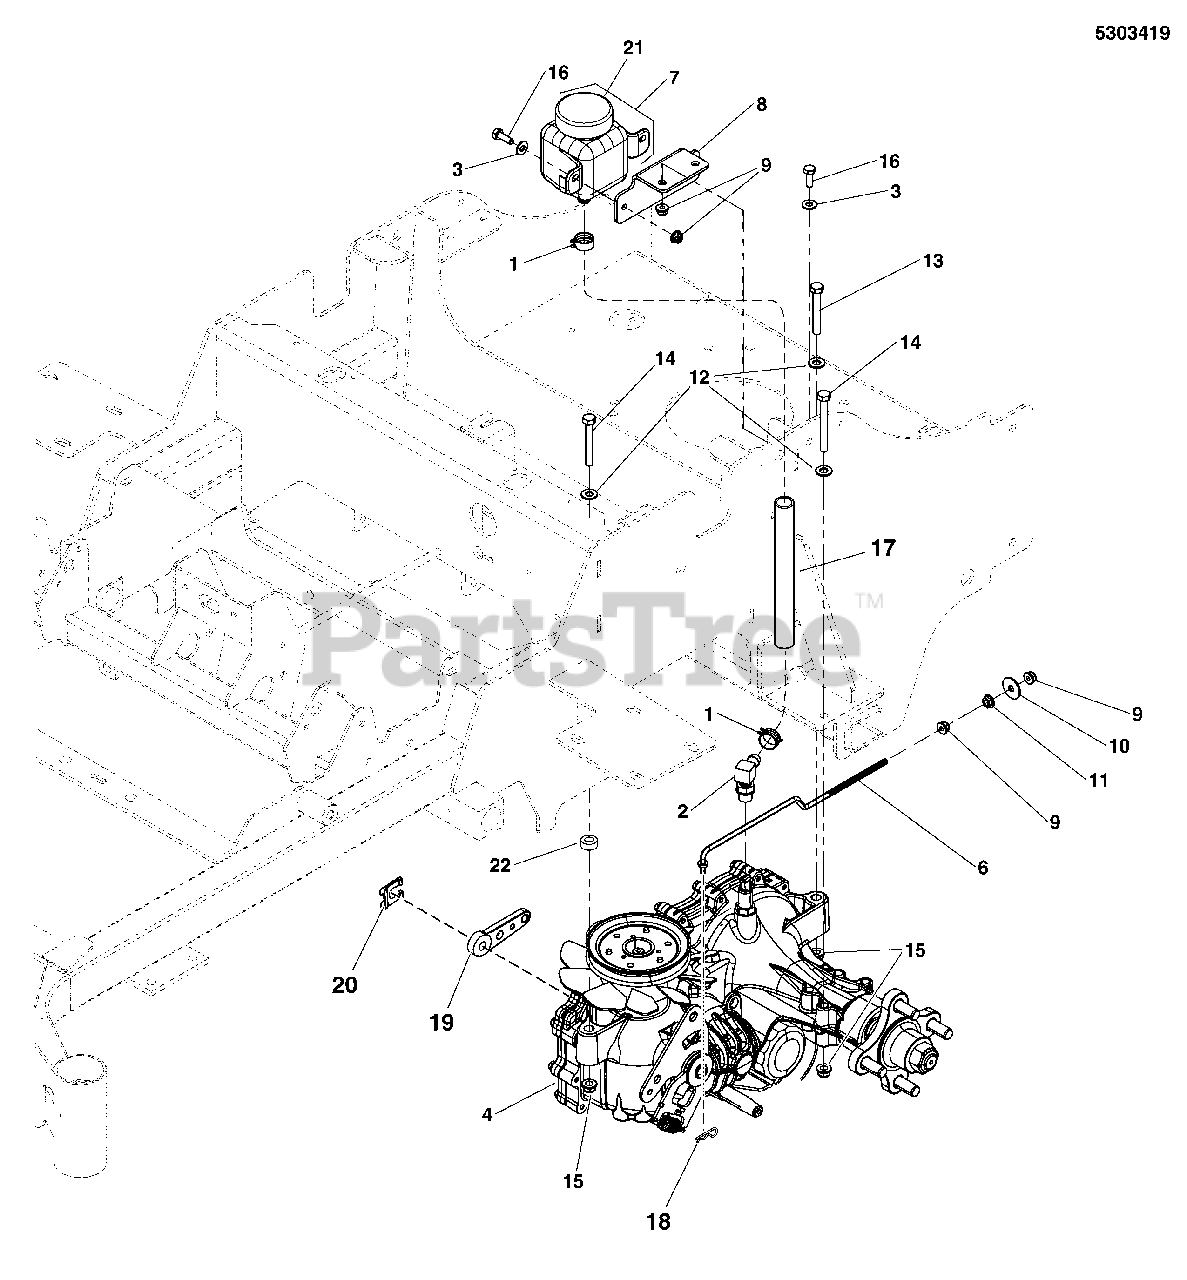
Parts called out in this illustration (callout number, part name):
1	CLAMP, HOSE, .75 FREE DIA.
2	FITTING, 9/16 O-RING-1/2" HOSE, 90 DEG
3	WASHER, Flat, 1/4
4	TRANSAXLE, ZT3100, LH, ZL-KMEF-3C7C-1PXX
5	TRANSAXLE, ZT3100, RH ZL-GMEF-3C7B-1PXX
6	ROD, DUMP VALVE, IS600, CZ
7	HYDRO RES. #71328, 350 ml
8	PLATE, HYDRO BOTTLE MOUNT - BLACK
9	NUT, Nylock Flanged, 1/4-20
10	WASHER, 1/4 FENDER
11	NUT, 1/4-20 HEX SERR. FLANGE
12	WASHER, 5/16 SAE
13	BOLT, 5/16-18 X 2-1/4 GD5 YZ
14	BOLT, 5/16-18 X 2-3/4, GD 5, YZ
15	NUT, 5/16-18 HEX NYLOCK FLANGE
16	BOLT, 1/4-20 X 3/4 GD5 YZ
17	HOSE, 1/2" PUSH-ON, 7.00"
18	PIN, HAIR, .0585 X 1-1/8, 1/4 EYE, YZ
19	ARM, Brake
20	CLIP, RETAINER, BRAKE ARM
21	RESERVIOR CAP (SV)
22	SPACER, .390 X .75 X .580, CZ
